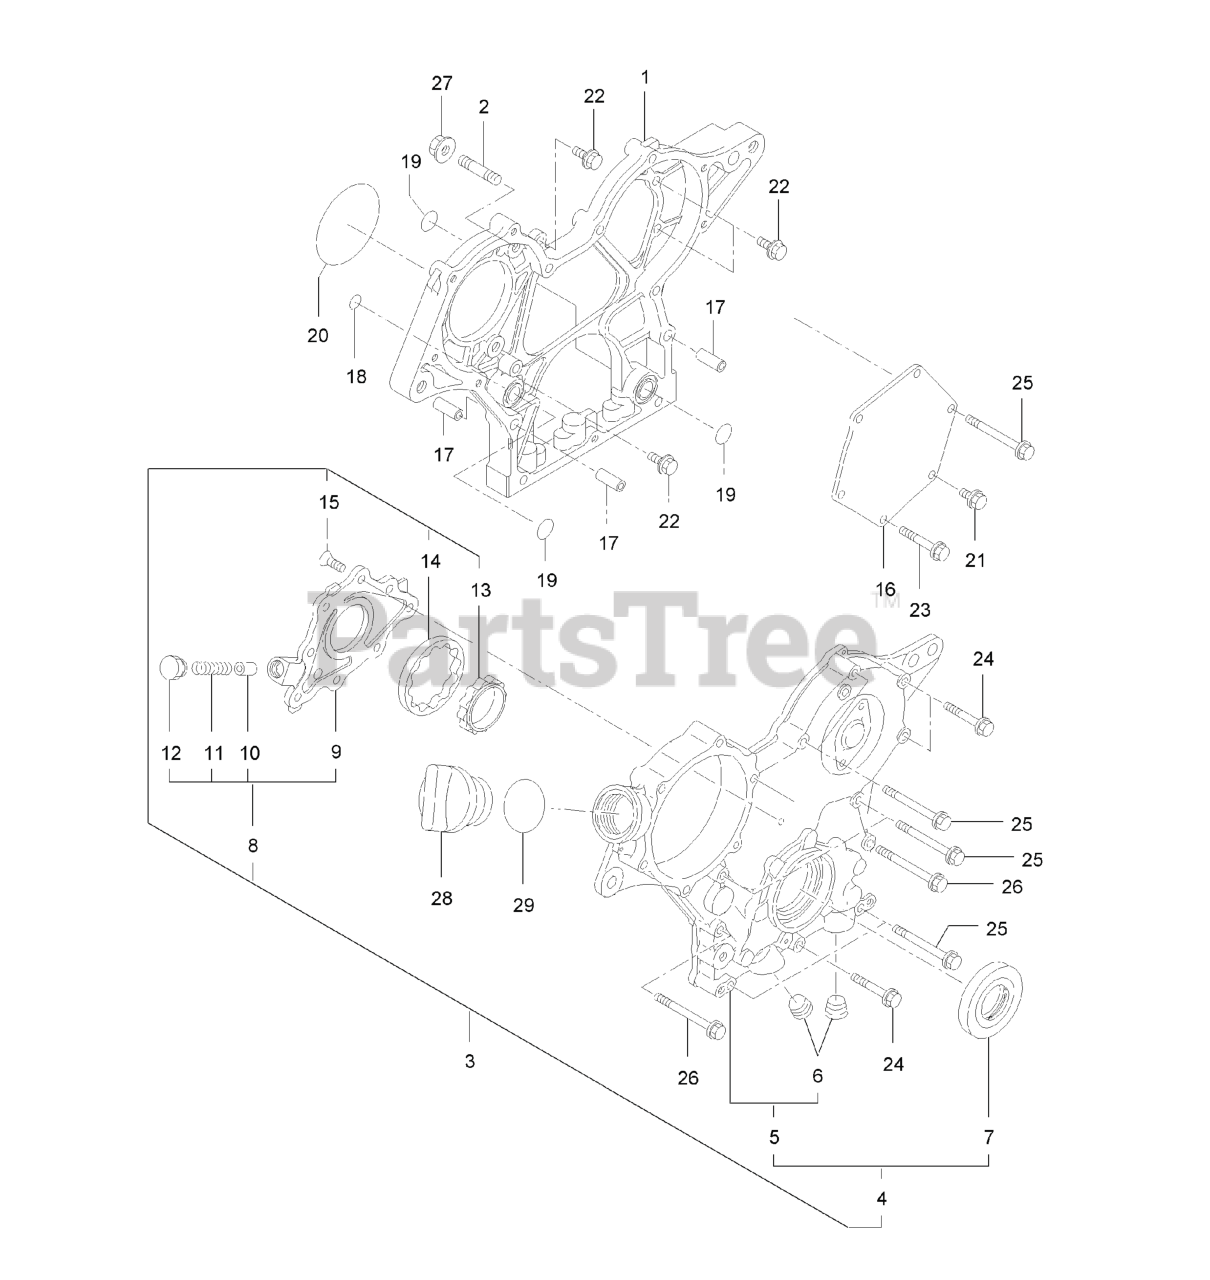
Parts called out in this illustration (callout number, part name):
1	CASE-GEAR
2	BOLT-STUD
3	COVER ASM-GEAR CASE
4	COVER ASSY-GEAR CASE
5	COVER-GEAR CASE
7	SEAL-OIL
8	COVER ASM
9	COVER-PUMP
10	VALVE-RELIEF
13	ROTOR-INNER
14	ROTOR-OUTER
16	COVER-PUMP
17	PIPE-DOWEL
28	COVER-FILLER
